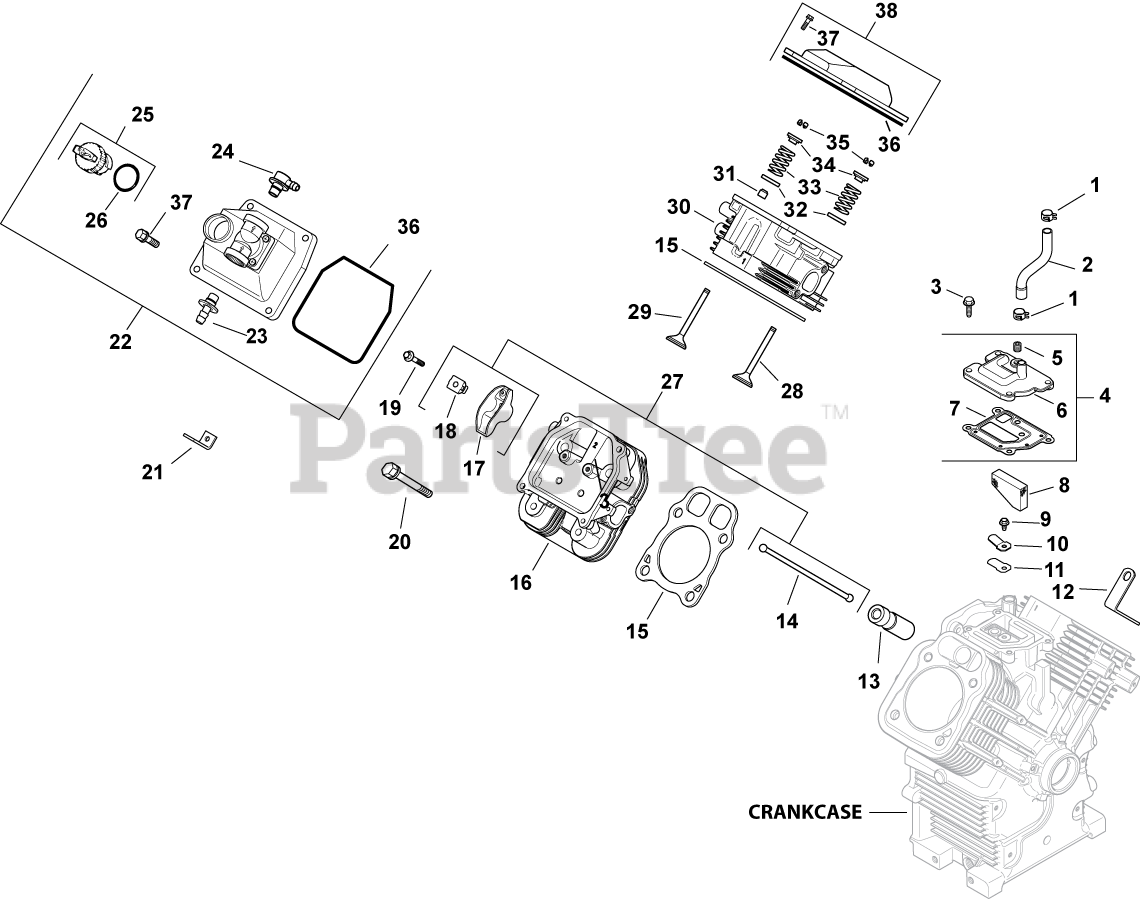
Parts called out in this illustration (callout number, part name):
1	CLAMP, BAND SPRING HOSE-(#2523737S)
2	HOSE, BREATHER
3	SCREW,FLG THD FRM M6X1.0X20-(#25086396S)
4	KIT, BREATHER ASSEMBLY
5	PLUG, CTSK PIPE 1/8"
6	COVER, BREATHER -USE 24 033 01-S
7	GASKET, BREATHER-USE 24 041 67-S
8	FILTER, BREATHER
9	SCREW, FLG THD FRM M5X.8X10
10	RETAINER, REED
11	REED, BREATHER
12	STRAP, LIFTING-USE 25 445 03-S
13	LIFTER, HYDRAULIC VALVE-USE 25 351 10-S
14	ROD, PUSH
15	KIT, CYL HEAD GASKET (C17-22)
16	HEAD, ASSEM CYLINDER #2 -USE 24 318 115-
17	ARM, ROCKER
18	PIVOT, ROCKER ARM
19	SCREW, FLG M6X1.0X34
20	SCREW, FLG M8X1.25X45
22	KIT, VALVE COVER-FUEL PUMP
23	KIT, STRAIGHT FITTING
24	KIT, 90 DEG. FITTING
25	CAP ASSY, OIL FILL (YELLOW)
26	O-RING-USE 24 153 32-S
27	KIT, VALVE TRAIN
28	VALVE, INTAKE (STD)
29	VALVE, EXHAUST (STD) - USE 32 016 01-S
30	HEAD, ASSEM CYLINDER #1 -USE 24 318 107-
31	SEAL, VALVE STEM - (#2503214S)
32	RETAINER, SPRING
33	SPRING, VALVE
34	RETAINER, VALVE SPRING - USE 25 173 28-S
35	KIT, RETAINER
36	O-RING (YELLOW), VALVE COVER
37	SCREW, FLG M6X1.0X30
38	KIT, VALVE COVER-PLAIN
2401602-S	VALVE, EXHAUST (.25)
2401702-S	VALVE, INTAKE (.25)
